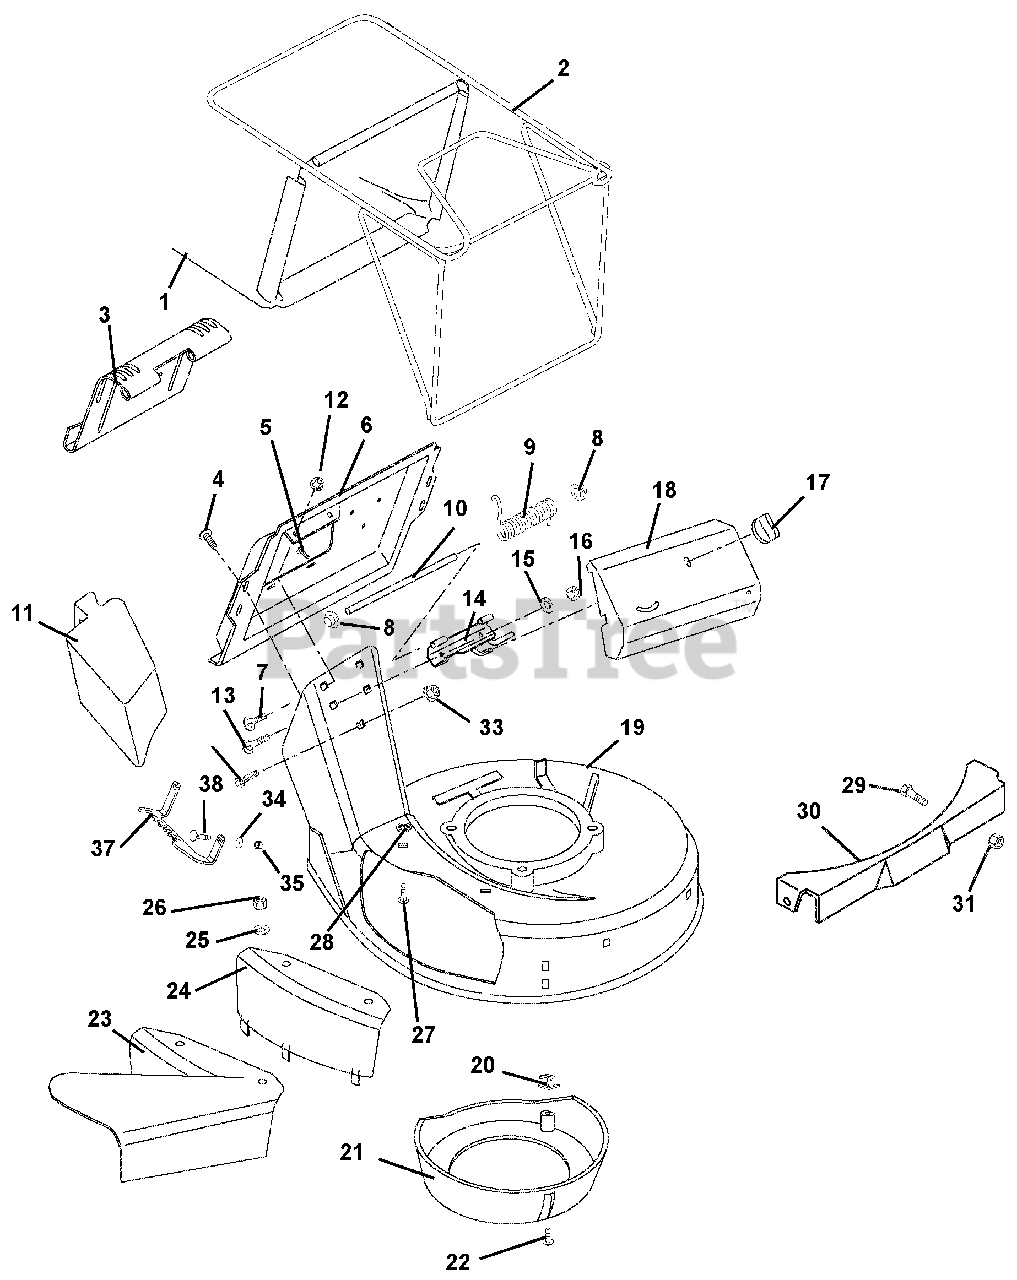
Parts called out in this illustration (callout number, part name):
1	Bag, Consumer Black
2	Frame, Bagger
3	Door, Catcher Plate
4	Screw, Tapping Hex Washer 12-24 x .50
5	Screw, Tapping 10-24 x .38 Pan Head
6	Plate, Catcher
7	Bolt, Round Head Square Neck .25-20 x .50 Grade 5
8	Nut, Push
9	Spring, Torsion .120 x .68 x 3.09
10	Pin, Door
11	Mulch Master Plug
12	Nut, Locking Flange .25-20 (911171)
13	Bolt, Round Head Square Neck .25-20 x .75 Grade 5
14	Hinge Base Weldment (911196, 197)
15	Washer, Locking .25 x .077
16	Nut, Hex .25-20
17	Nut, Wing (911196, 197)
18	Drive Cover (911196, 197)
19	Mower Pan Head with Decals (911196, 197)
20	Grommet, Plastic
21	Baffle, Center
22	Screw, Tapping 10-16 x .62 Hex Washer Head
23	Side Discharge Assembly
24	Side Discharge Cover
25	Washer, Flat Steel .406 x .812 x .065
26	Nut, Locking Nylon .312-18
27	Bolt, Round Head Square Neck .31-18 x .75 Grade 2 (911196, 197)
28	Nut, Push .312
29	Bolt, Round Head Square Neck .31-18 x .50 Grade 5 (911196, 171)
30	Front Panel (911196, 171)
31	Nut, Locking-Top-Flange .31-18 (911196)
32	Bolt, Hex .38-16 x .50 Grade 5 (911171)
33	Nut, Locking Flange Nut, .375-16 (911171)
34	Washer, Flat Steel .38 x .875 x .083 (911171)
35	Nut, Locking Center .25-20
36	Bolt, Hex .25-20 x .50 Grade 5 (911171)
37	Bracket, Speed Slection (911196, 197)
38	Bolt, Round Head Square Neck .25-20 x .50 Grade 5
